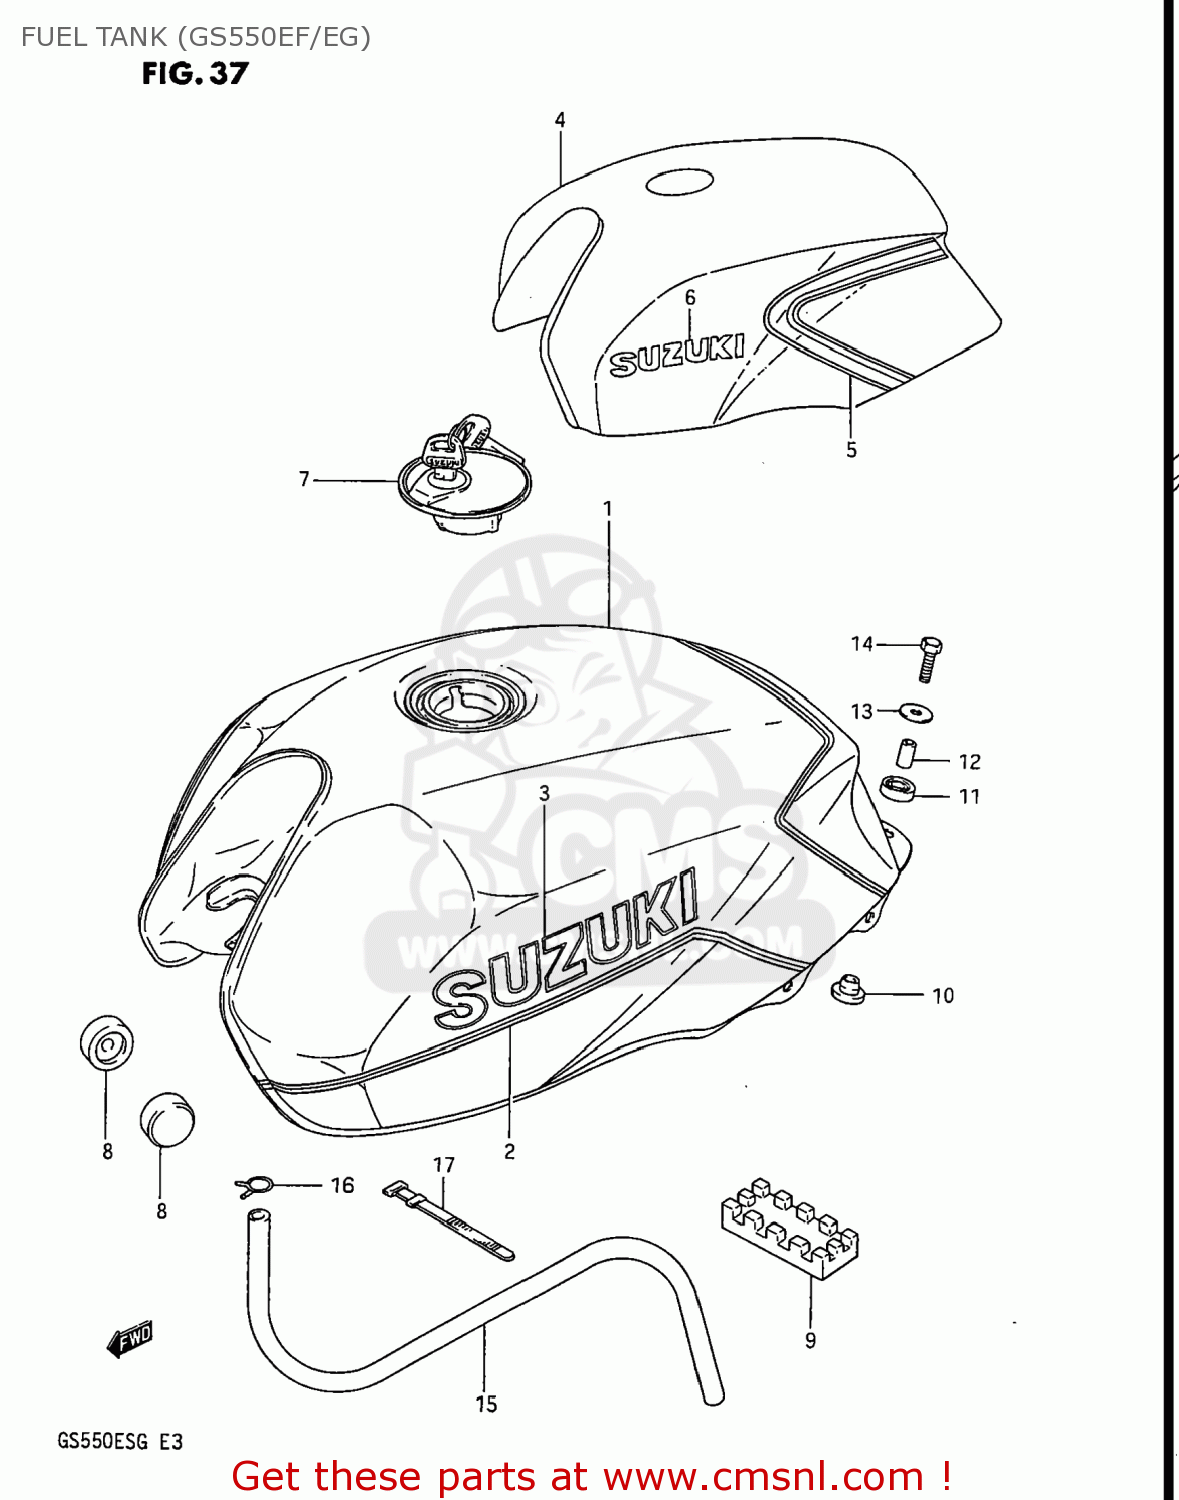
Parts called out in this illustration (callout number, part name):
1	TANK ASSEMBLY,FUEL
2	TAPE SET,FUEL TANK
3	EMBLEM
4	TANK ASSEMBLY,FUEL
5	TAPE SET,FUEL TANK
6	EMBLEM
7	CAP SET,FUEL TANK
8	CUSHION
9	CUSHION,FUEL TANK
10	CUSHION
11	CUSHION
12	SPACER (6.4X9X20)
13	WASHER (6.5X24X1.6)
14	BOLT
15	HOSE,FUEL
16	CLIP
17	CLAMP(L:187)
